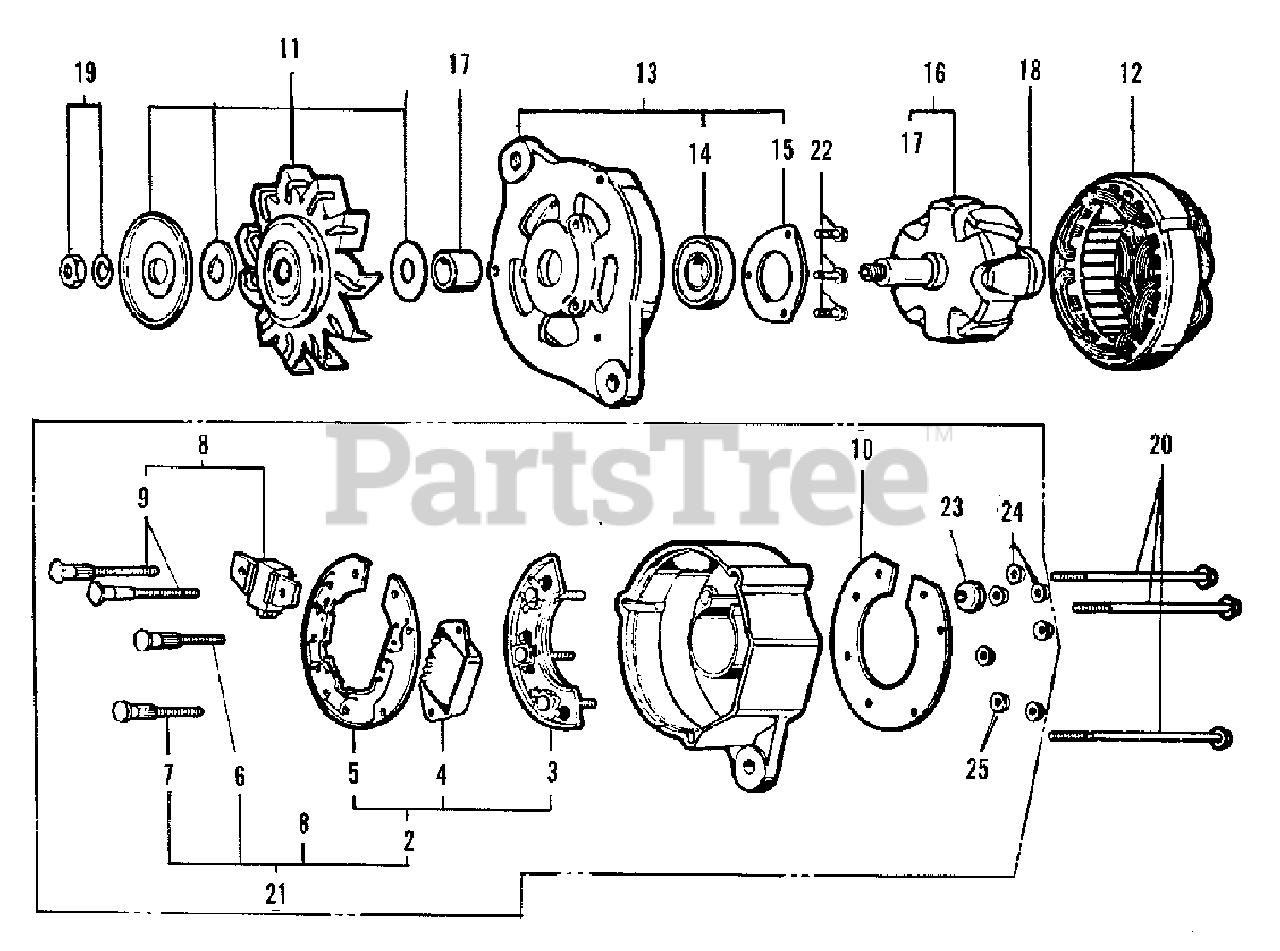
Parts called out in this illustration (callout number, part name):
1	COVER ASSEMBLY, rear (Incl. Items 10, 21 & 23 thru 25)
2	REGULATOR ASSEMBLY, diode (Incl. 3 thru 5)
3	DIODE ASSEMBLY (Not serviced; order 2098379 REGULATOR ASSEMBLY)
4	REGULATOR ASSEMBLY, I.C. (Not serviced; order 2098379 REGULATOR ASSEMBLY)
5	PLATE, diode (Not serviced; order 2098379 REGULATOR ASSEMBLY)
8	BRUSH ASSEMBLY (Incl. Item 9)
9	BOLT, M4 x 38
11	PULLEY ASSEMBLY
12	STATOR ASSEMBLY
13	COVER ASSEMBLY, front (Incl. Items 14 & 15)
14	BEARING, ball
15	RETAINER, bearing
16	ROTOR ASSEMBLY (Incl. Item 17)
18	BEARING, ball
19	NUT ASSEMBLY, pulley
20	BOLT, through
21	BRUSH ASSEMBLY, diode (Incl Items 2 thru 9) (Not serviced; order 2098379 REGULATOR ASSEMBLY)
22	CAPSCREW ASSEMBLY, M4 x 12
24	NUT ASSEMBLY, M4
25	NUT ASSEMBLY, M5
